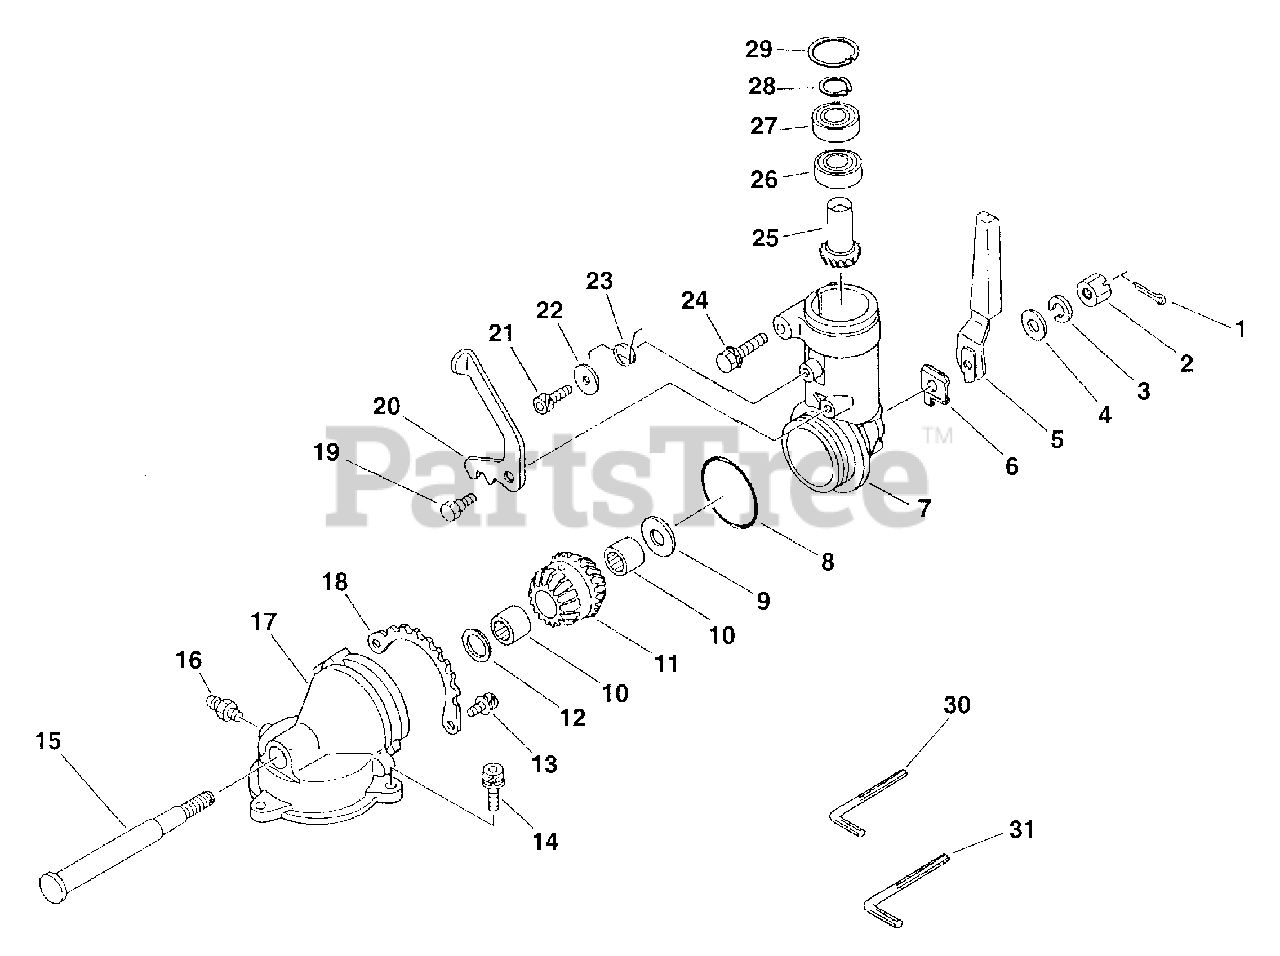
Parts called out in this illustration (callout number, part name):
1	PIN, SPLIT - 1.6X16
2	NUT - 6 -- SLOTTED
3	LOCKWASHER - 6
4	WASHER, THRUST
5	PIECE, LEVER
6	PLATE, ANGLE
7	CASE, GEAR
8	O-RING - 32
9	WASHER
9	WASHER - 8
10	BEARING, NEEDLE - 8
11	GEAR - BEVEL
12	WASHER
12	WASHER - 10
13	SCREW - 4X10
14	SCREW - 5X18
15	GEAR - SHAFT
16	FITTING, GREASE
17	LID, GEAR CASE
18	RESETTER, LATCH
19	BOLT - 5
20	PAWL
21	SCREW - 5X14
22	WASHER - 5
24	BOLT - 5X35
25	GEAR - DRIVE
26	BEARING, BALL - 6900
27	BEARING, BALL - 6900Z
28	RING, RETAINING - 10
29	RING, RETAINING - 22
30	HEX KEY - 3mm
31	HEX KEY - 4mm
